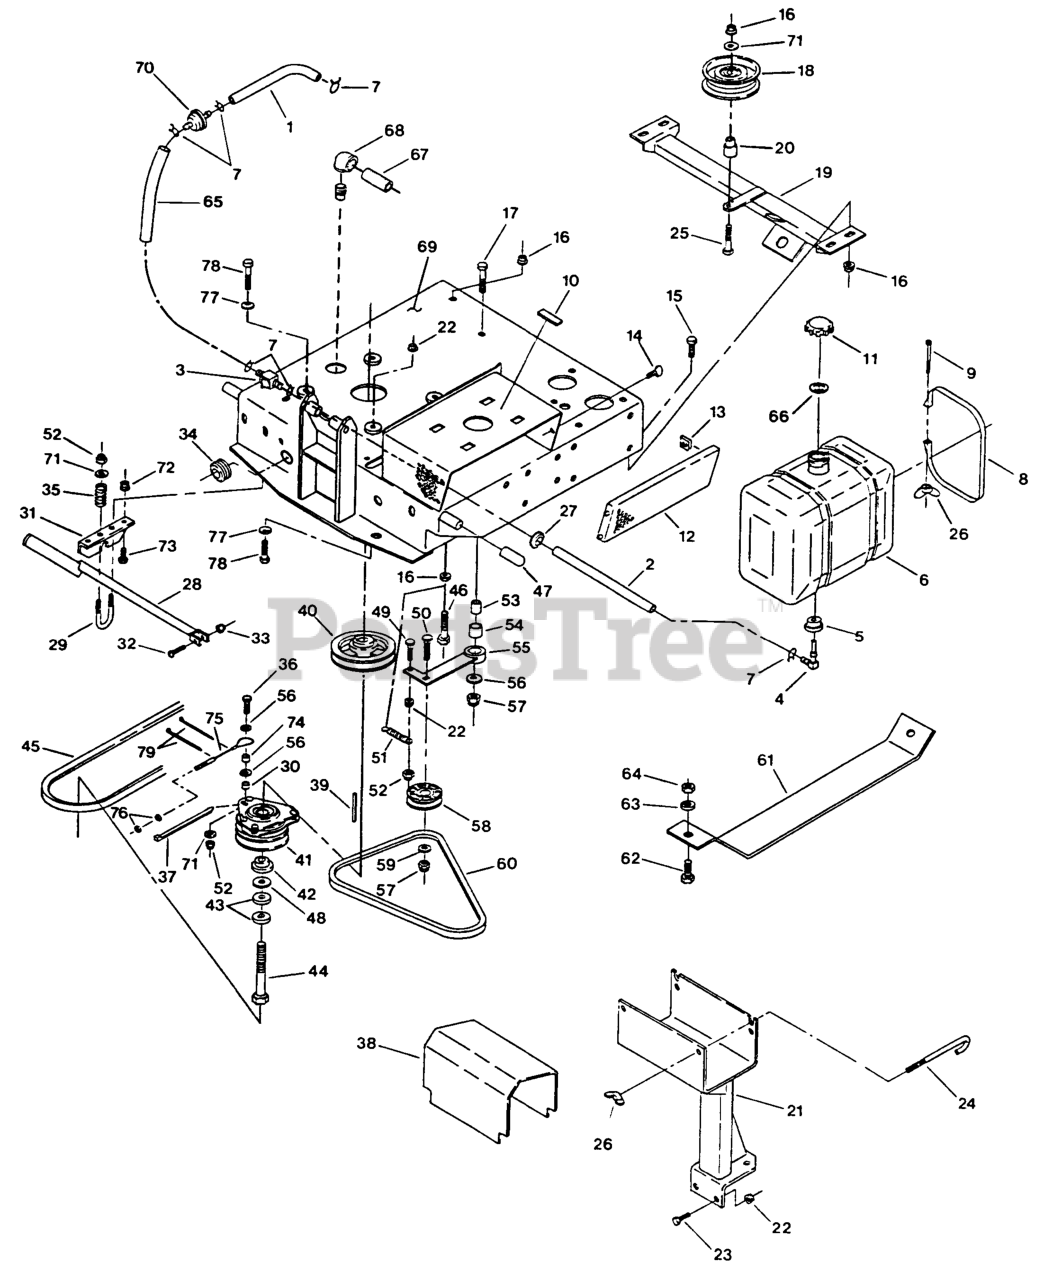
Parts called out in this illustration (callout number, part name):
1	FUEL LINE
3	VALVE-FUEL
4	ELBOW-TANK, FUEL
10	PAD,PLASTIC TANK
11	CAP-FUEL
13	NUT,RETNR UTYP 1/4-20
14	SCREW,REGTHMB,
19	WLD,CROSSMEMBER
20	BUSHING,IDLER
21	WLD,BATTERY MOUNT
24	BOLT - HOLD DOWN
26	WINGNUT
27	GROMMET
30	SPACER,CLUTCH ANCHOR
33	NUT-LOCK, HH
34	GROMMET
35	SPRING-COMPRESSION
37	TIE-PLASTIC
40	SHEAVE,4.25 OD A
42	BUSHING,CLUTCH KEEPER
43	WASHER-SPRING
45	BELT,BLADE DRIVE
47	GRIP-LEVER, DRIVE
51	SPRING,EXTENSION
53	BUSHING,STEEL
54	BUSHING,IDLER ARM
55	WLD,IDLER ARM HYDRO
58	IDLER,PULLEY
60	BELT,A TRANS DRIVE
61	PLATE-SKID
67	NIPPLE,PIPE
68	ELBOW-90 DEG
77	WASHER-SPRING
79	TIE-CABLE
